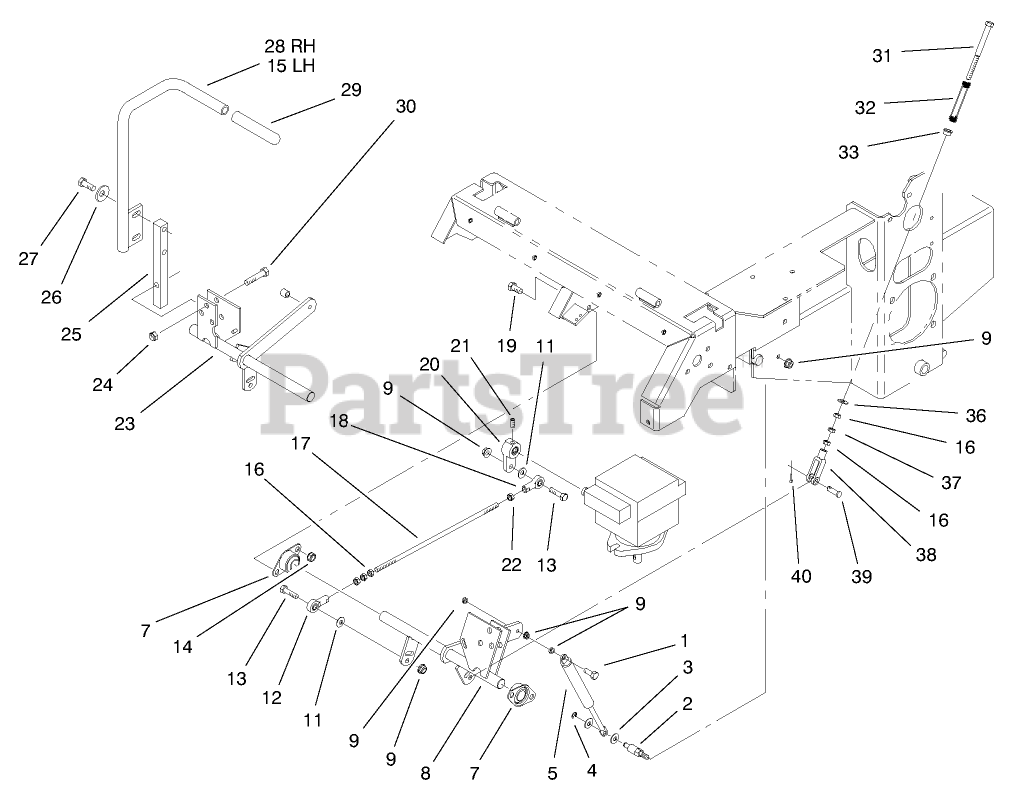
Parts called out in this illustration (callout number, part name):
1	SCREW-HH
2	Pin-Dampner
3	WASHER-PLAIN
4	E-Ring
5	Damper
7	Bearing-Side Flange
8	Motion Control, LH
9	NUT-HF
11	WASHER-FLAT
12	Ball Joint
13	SCREW-HH
14	NUT-HHF, WHIZ
15	Lever-LH
16	NUT-HEX
17	Link-Pump Control
18	Ball Joint LH
19	SCREW-HH
20	Arm-Pump Control
21	Screw
22	Nut
23	Motion Control, RH
24	NUT-LOCK, NI
25	Arm
26	Washer
27	SCREW-HH
28	Lever-RH
29	Grip
30	SCREW-HH
31	Bolt
32	Spring
33	Bushing
36	WASHER-FLAT
37	NUT-JAM
38	Yoke
39	Pin-Clevis
40	PIN-COTTER
